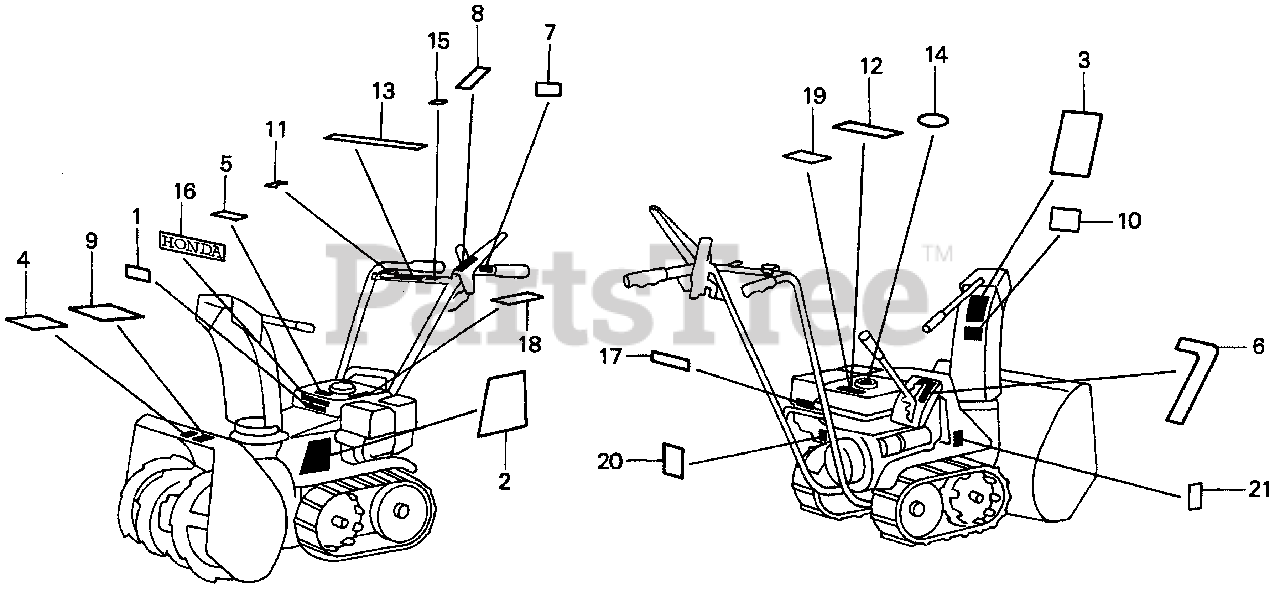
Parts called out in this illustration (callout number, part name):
2	MARK, MAIN EMBLEM (HS622)
4	LABEL, WARNING (ENGLISH)
5	LABEL, WARNING FUEL (ENGLISH)
6	LABEL, CHANGE INDICATION
7	MARK, CLUTCH (A)
8	MARK, AUGER CLUTCH (ENGLISH)
9	MARK, HOUSING DANGER (ENGLISH)
10	MARK, DISCHARGE DANGER (ENGLISH)
11	MARK, ENGINE SWITCH INDICATION (ENGLISH)
12	LABEL, STARTER OPERATION (A)
13	LABEL, OPERATION
16	MARK, HONDA (120)
17	MARK, THROTTLE INDICATION
18	MARK, EX. CAUTION (ENGLISH)
19	MARK, FUEL (EXTERNAL)
20	MARK, FUEL INDICATION (ENGLISH)
21	MARK, OIL CAUTION
